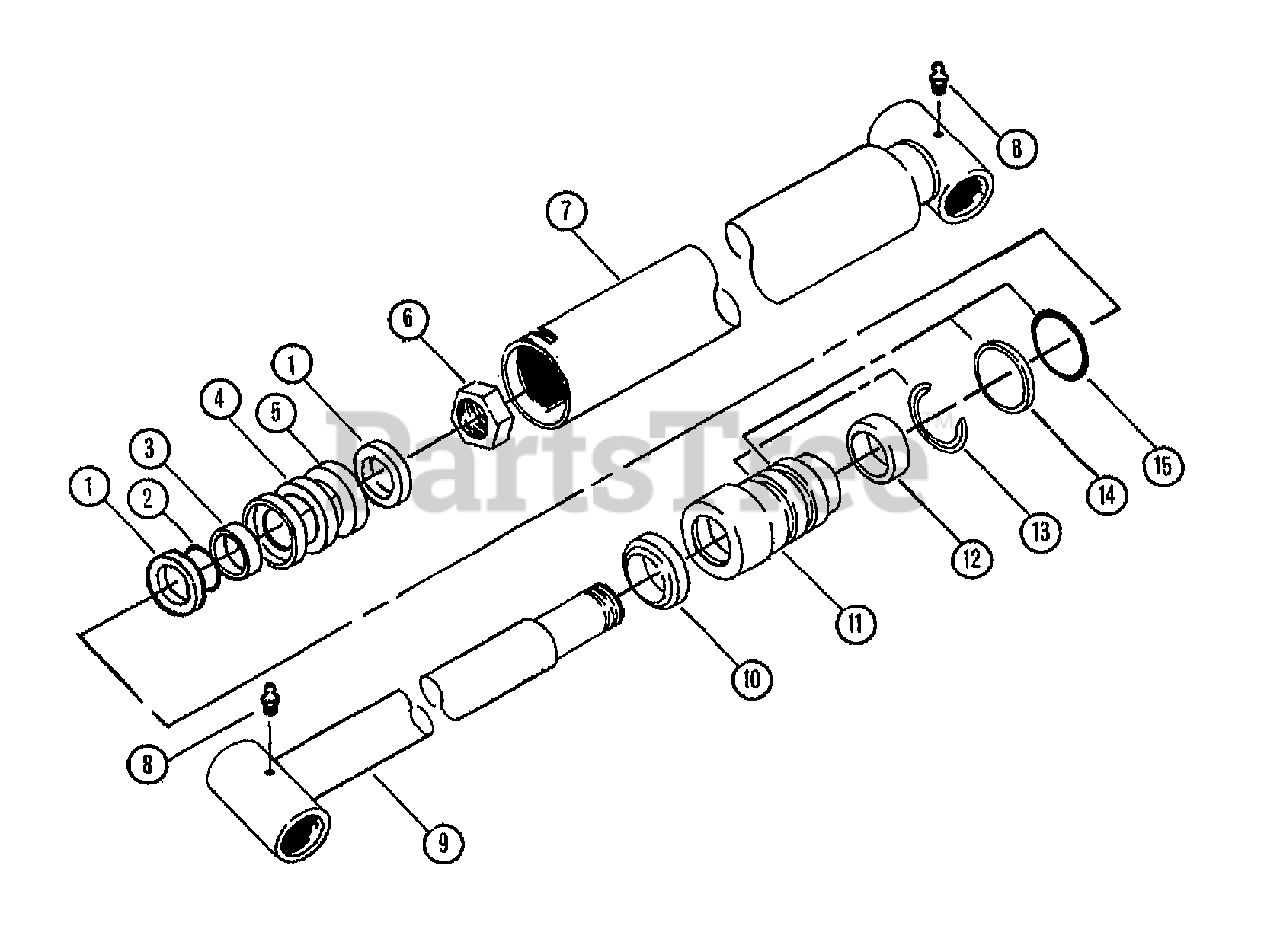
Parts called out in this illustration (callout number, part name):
1	PISTON END
6	LOCKNUT
7	ASSM-BODY
8	FITTING-GREASE 1/4-28X2.00
